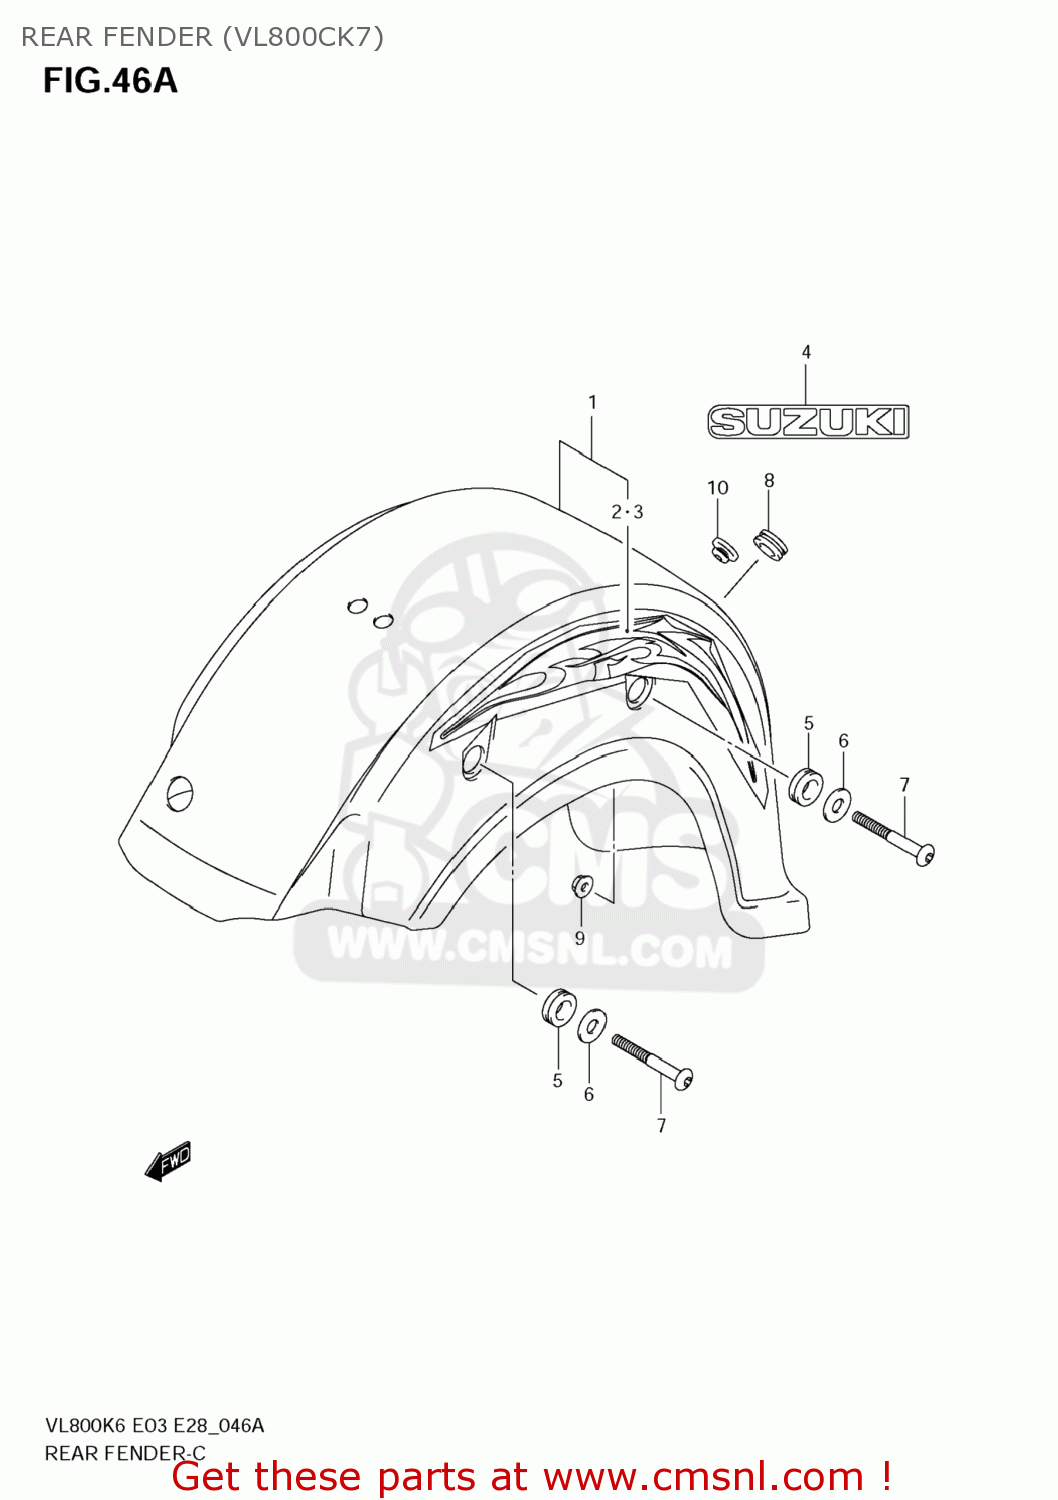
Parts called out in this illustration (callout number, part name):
1	FENDER,RR
2	TAPE,RR FENDER,R
3	TAPE,RR FENDER,L
4	EMBLEM,SUZUKI
5	CUSHION,FRAME COVER UPR RR
6	WASHER(15.5X26X2.3)
7	BOLT,RR FENDER
8	CUSHION
9	NUT
10	CUSHION
